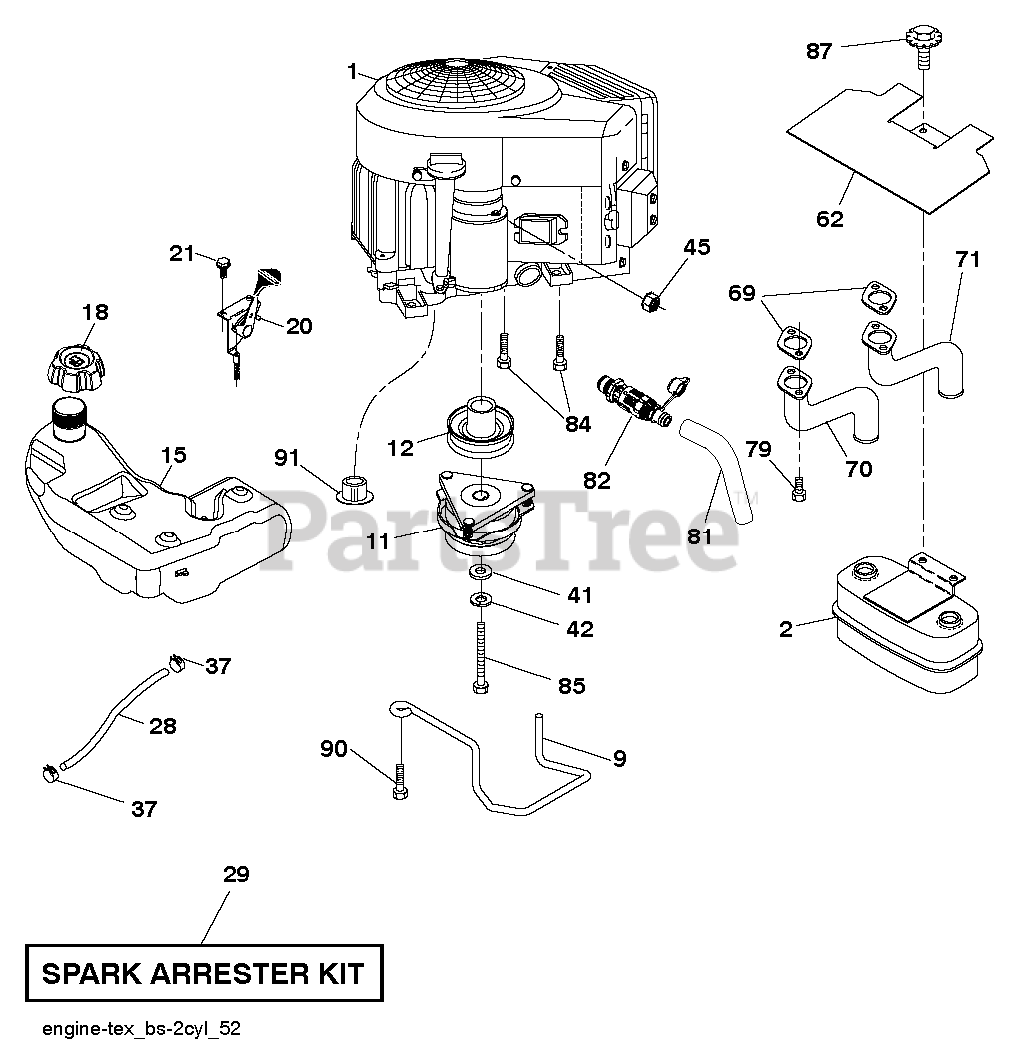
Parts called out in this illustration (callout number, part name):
2	MUFFLER.TWIN.CYL.LOW.TONE
9	KEEPER.BELT.ENGINE.4.2
11	CLUTCH.ELECTRIC.LT.48"*
12	PULLEY.ENGINE.TUFFTORQ
15	RP_TANK.ASSY.3.GAL.EPA
18	CAP.ASM.FL.RITCH.3"E10.SYM.498
20	CONTROL.TH/CK.COBRA.B&S.TWN.BK
21	SCREW.#10 X 0.750.BOS
28	LINE.FUEL.64"REAR.EMIS
29	KIT.SPARK ARRESTOR 794945 B&S
37	HOSE CLAMP
42	LOCKWASHER
45	NUT
62	SHIELD.HEAT.MUFFLER
69	GASKET.MUFFLER
70	EXHAUST.TUBE.LH.BS/TWIN
71	EXHAUST.TUBE.RH.B&S.TWIN.INTEK
79	SCREW.SOCKET.HEAD.5/16-18
81	TUBE, DRAIN OIL ASM.
82	VALUE.OIL.DRAIN
84	SCREW.3/8-16
85	BOLT HEX 7/16-20X4-1/4"
87	BOLT.5/16-18UNCX3/4 W/SEMS.BLK
90	SCREW 3/8-16X1
91	BUSHING.1.375OD
